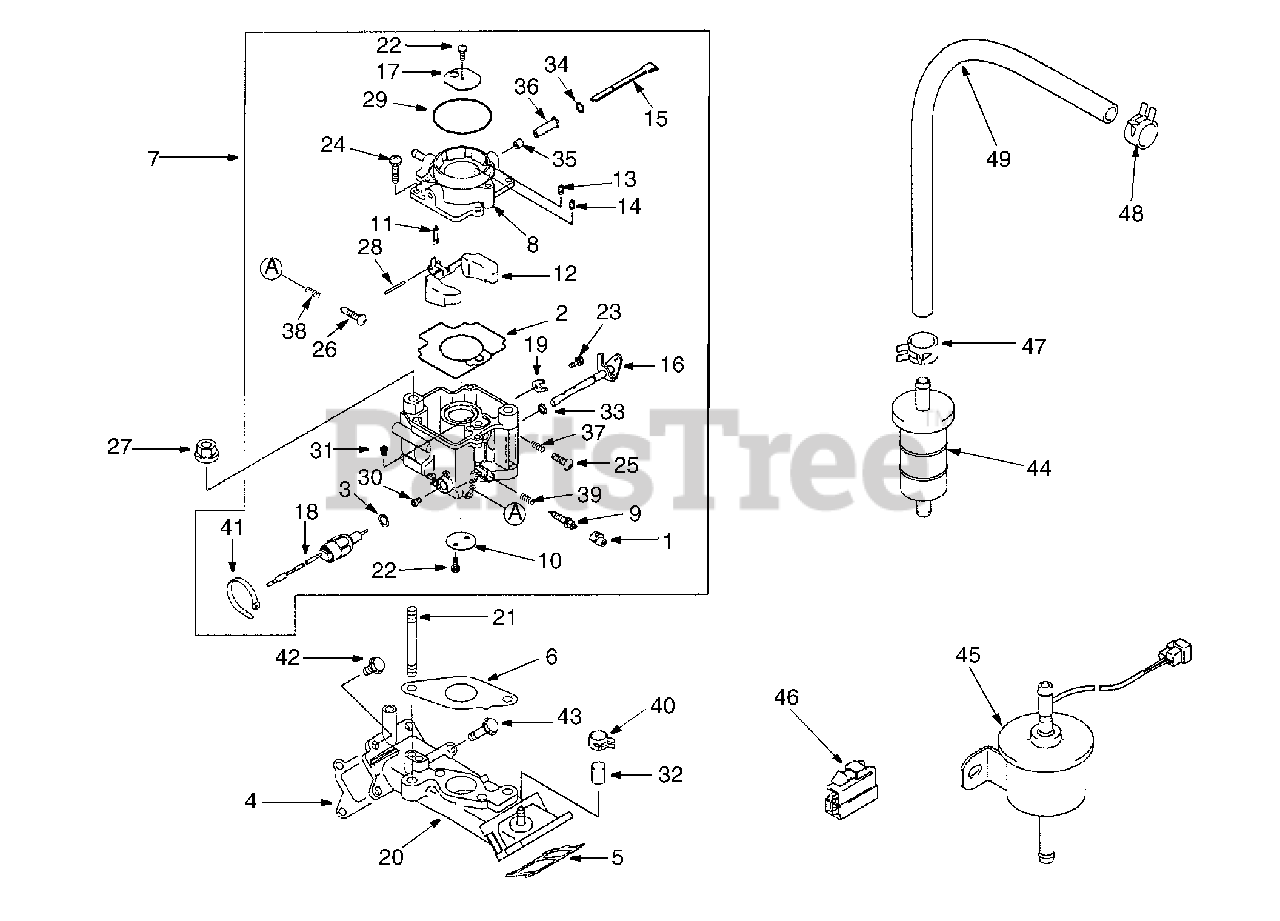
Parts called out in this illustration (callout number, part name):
4	Gasket, Intake Manifold
5	Gasket, Intake Manifold
6	Gasket, Carburetor
7	Carburetor Ass'y
9	Screw, Pilot Air
10	Valve, Throttle
13	Jet, Air, #1.8
14	Jet, Air, #0.9
16	Shaft, Throttle
18	Solenoid, Fuel
20	Manifold, Intake
22	Screw, 3 x 5.5
29	O-Ring, 49.4 MM
30	Jet, Main #112
31	Jet, Pilot, #58
33	Seal, Throttle Shaft
34	Seal, Choke Shaft
42	Bolt, Flanged 6 x 20
43	Bolt, Flanged 6 x 45
44	Filter, Fuel
46	Connector, Cord
